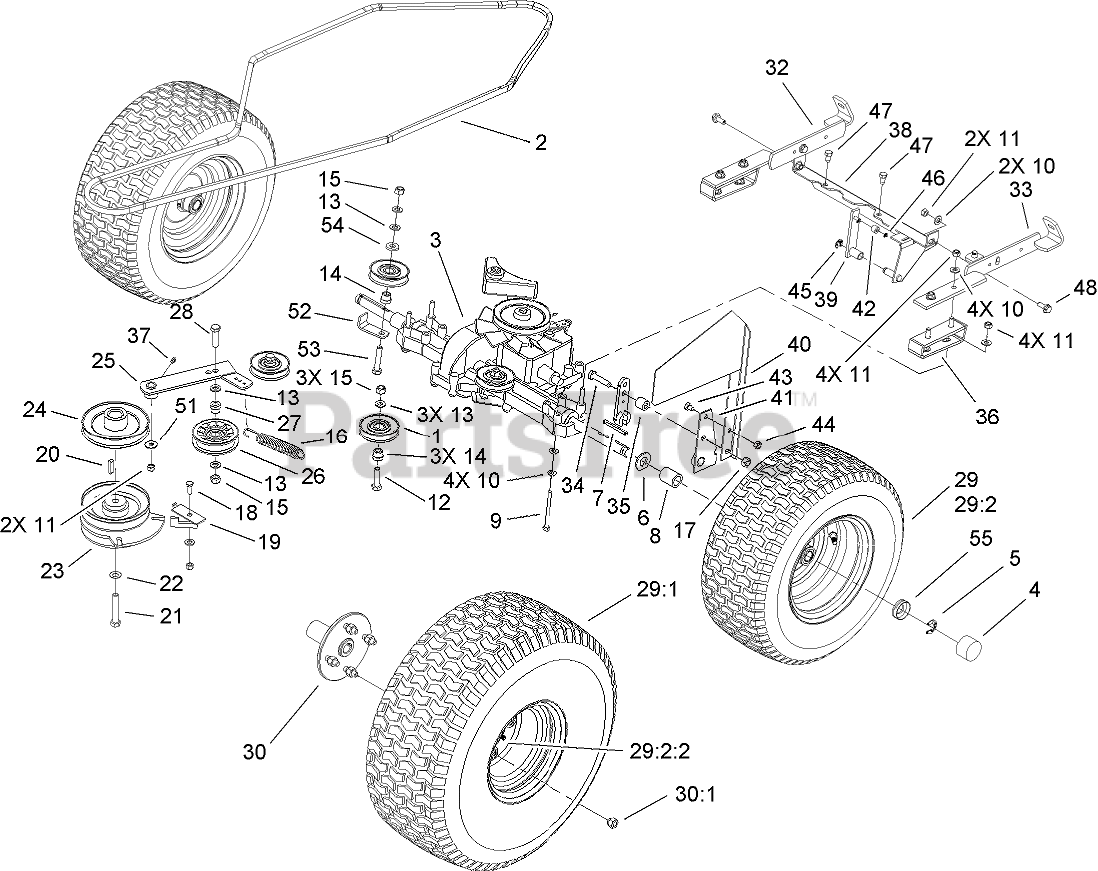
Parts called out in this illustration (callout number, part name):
1	PULLEY-IDLER
2	V-BELT-TRACTION
3	TRANSMISSION
4	CAP-HUB
5	CLIP-SPRING
6	WASHER
7	KEY-SQUARE
8	SPACER-AXLE
9	SCREW-HH
10	WASHER-PLAIN
11	NUT-LOCK, NI
12	SCREW-HH
13	WASHER-FLAT
14	BUSHING-IDLER
15	NUT-LOCK, NI
16	SPRING
17	NUT-LOCK, NI
18	SCREW-HH
19	RETAINER
20	KEY-SQUARE
21	SCREW-HH
22	WASHER-SPRING, BELLEVILLE
23	CLUTCH-ELECTRIC
24	PULLEY-ENGINE
25	ARM-IDLER
26	PULLEY-IDLER
27	BUSHING-IDLER
28	SCREW-HH
29	TIRE AND WHEEL ASM
29:2	WHEEL ASM
29:2:1	Rim
29:2:2	Valve-Tire
30	HUB-WHEEL
30:1	NUT-LUG
32	Bracket-Right
33	Bracket-Left
34	SCREW-HH
35	SLEEVE
36	Plate-Reinforcing
37	FITTING-GREASE
38	Bar ASM
39	Arm-Switch
40	ARM-CONTROL, CRUISE
42	Roller
43	SCREW-HH
44	NUT-LOCK, NI
45	Stirrup
46	STIRRUP
47	SCREW-THREAD FORMING
48	SCREW-HEX
51	WASHER-PLAIN
52	RETAINER-BELT
53	SCREW-HH
54	WASHER-FLAT
55	RETAINER-CAP, HUB
